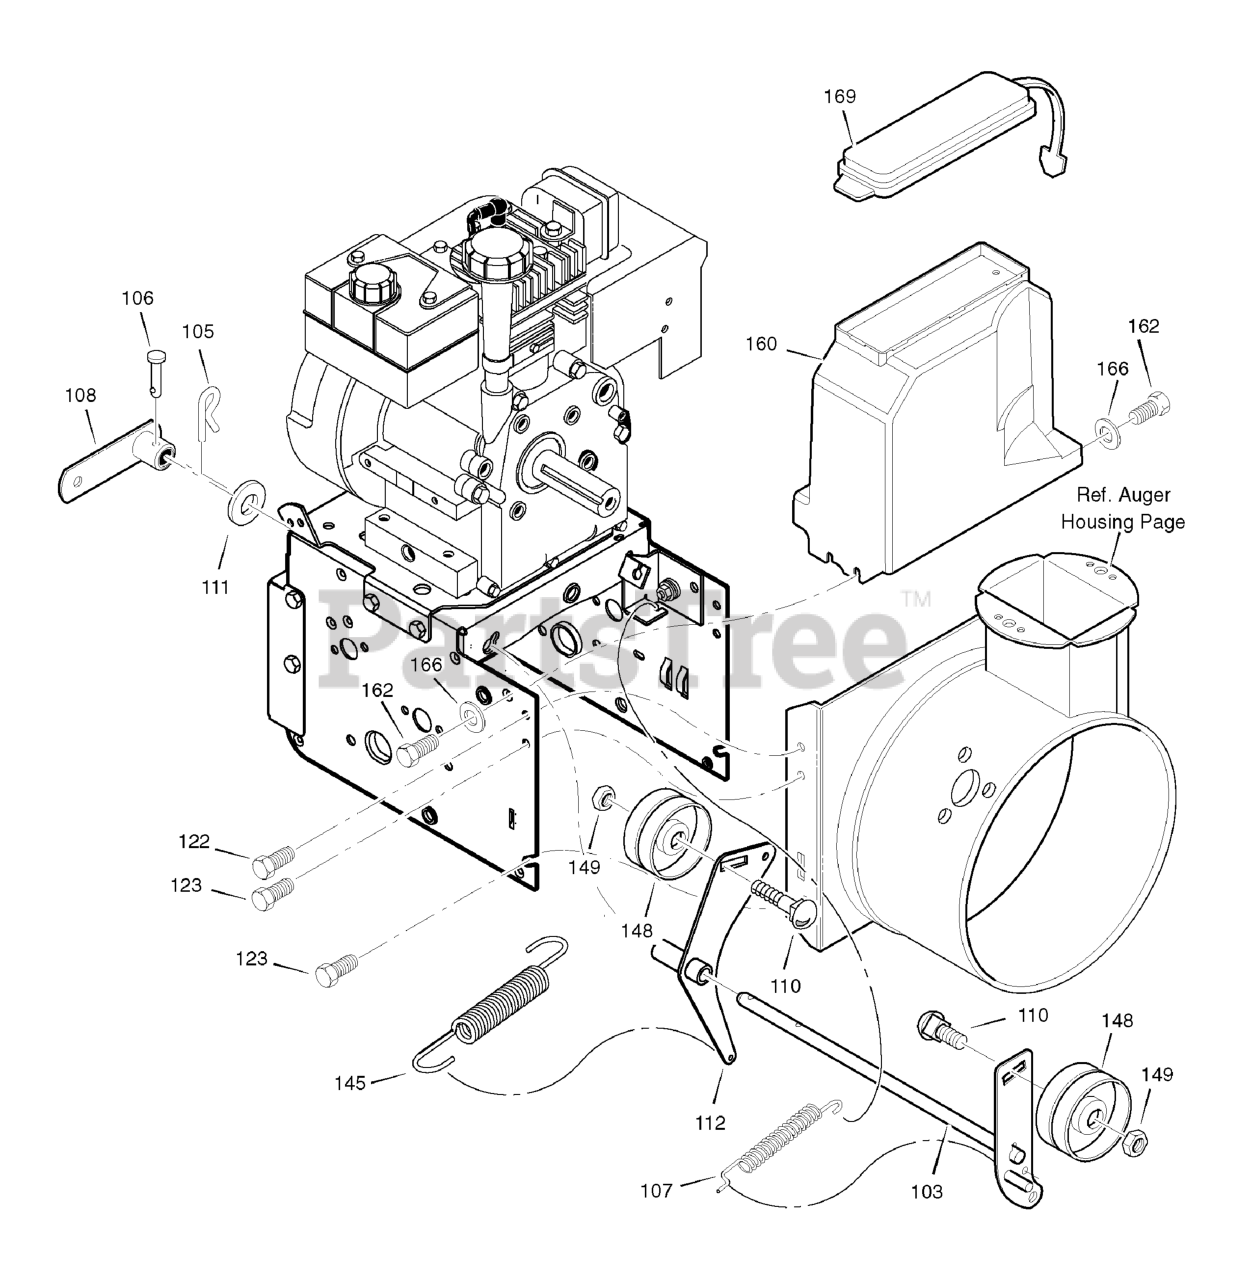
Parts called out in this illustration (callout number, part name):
90	COVER, BOTTOM
91	SCREW, 1/4-20 X .63
103	IDLER ASSEMBLY, AUGER
105	PIN, HAIR .38DIA X 1.64LG
106	PIN, CLEVIS 3/16" DIA
107	SPRING, TENSION
108	ARM CONTROL ASSEMBLY
110	BOLT, 3/8-16 X 1.25 CARRIAGE
122	SCREW, TAP 5/16-18 X .75
123	SCREW, TAP 5/16-18 X .50
148	PULLEY, IDLER
149	NUT, JAM 3/8-16
160	COVER, BELT
162	SCREW, TAP
167	WASHER, FLAT
168	SPACER, AUGER BRACKET
